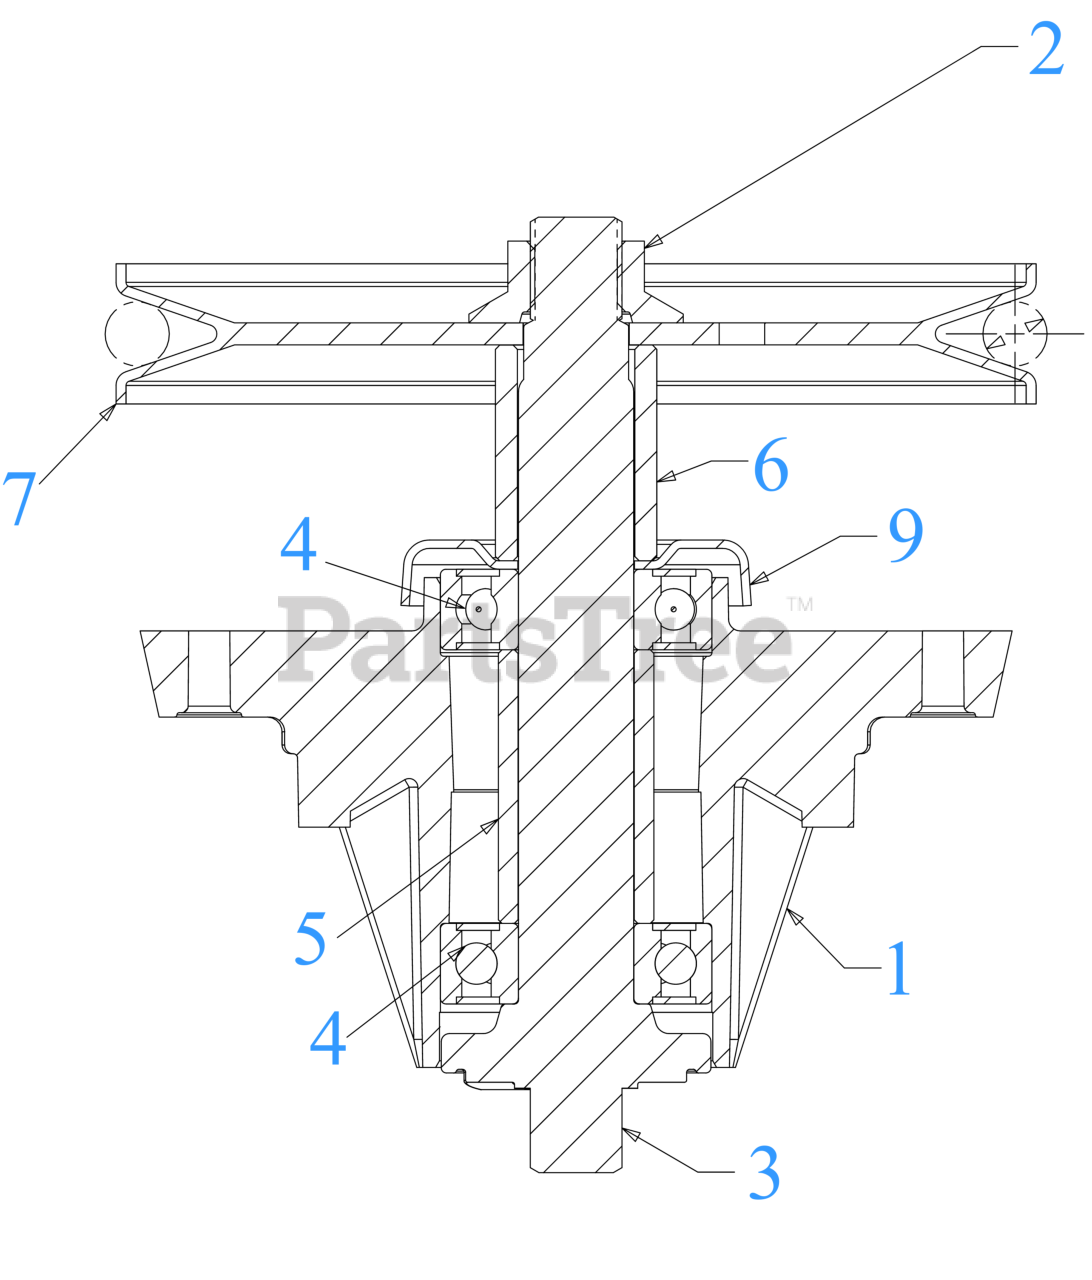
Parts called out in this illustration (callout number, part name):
1	DECK SPINDLE HOUSING
2	FLANGE NUT 5/8-18
3	SPINDLE SHAFT
4	BALL BEARING
5	SPACER- .792 x 1.060 x 1.860
6	SPACER .800 x 1.100 x 1.470 LG
7	DECK PULLEY 6.74" DIA
9	SHIELD-BRG DECK
